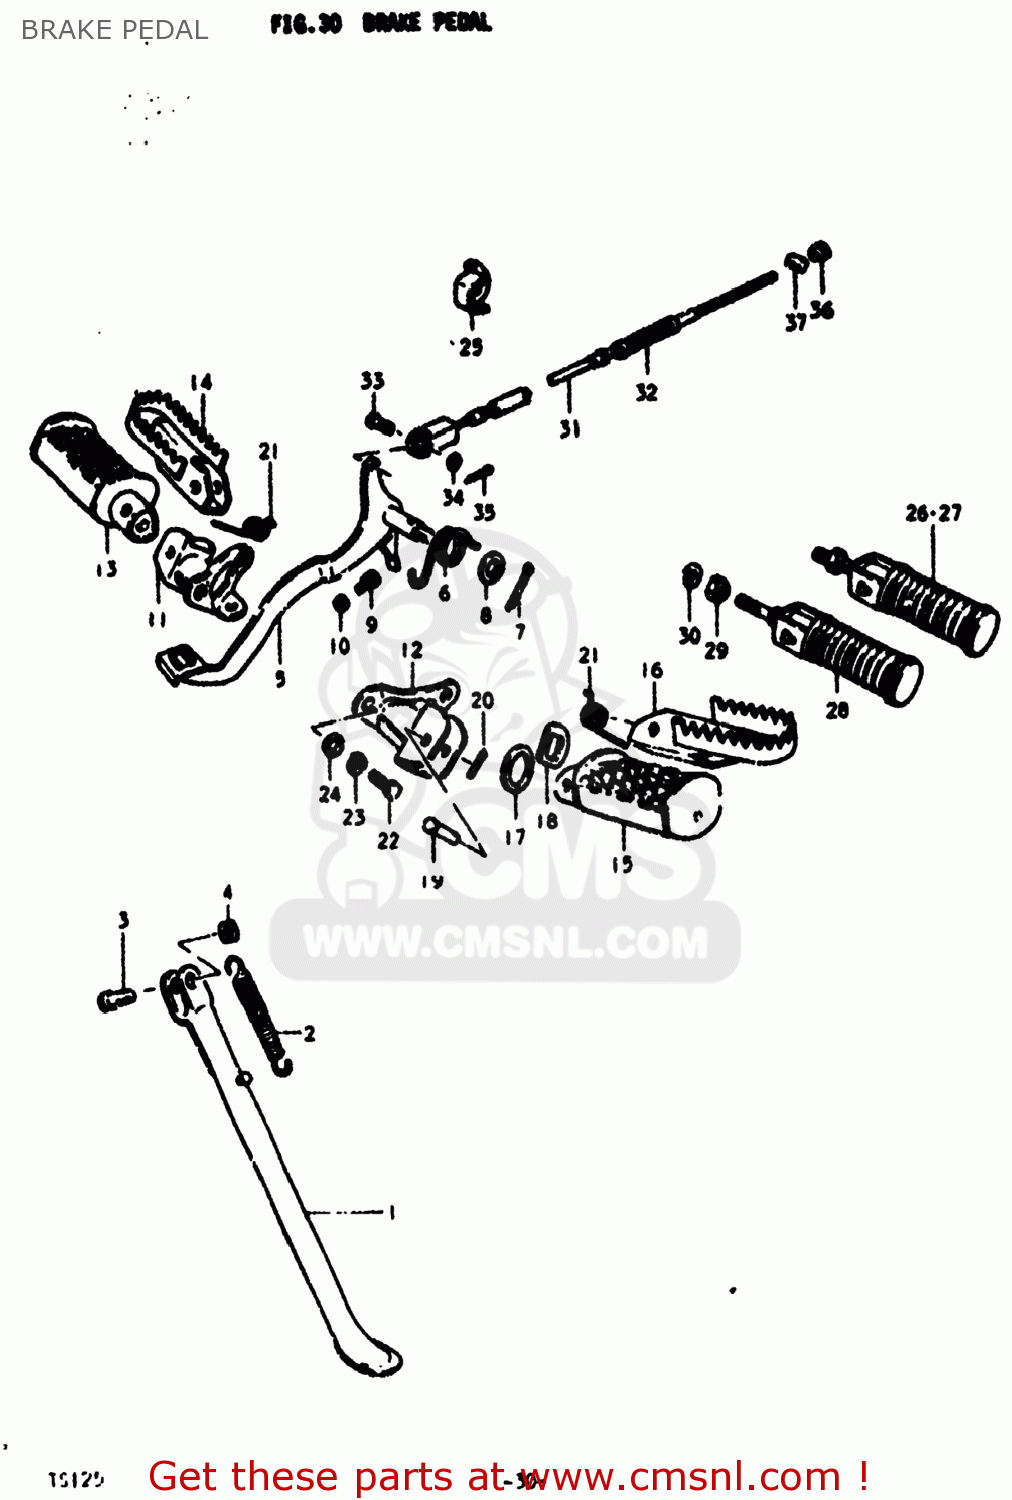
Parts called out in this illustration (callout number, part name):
1	STAND,SIDE
2	SPRING
3	BOLT(10X30)
4	NUT
5	PEDAL,BRAKE
6	SPRING
7	COTTER PIN
8	WASHER(15.5X26X2.3)
9	BOLT
10	NUT
11	BAR,FRONT FOOTREST
12	HOLDER,FRONT FOOTREST
13	RUBBER,FOOTREST,RIGHT
14	RUBBER,FOOTREST,RIGHT
15	RUBBER,FOOTREST,LEFT
16	RUBBER,FOOTREST,LEFT
17	WASHER
18	WASHER
19	PIN
20	PIN 20X20
21	SPRING
22	BOLT
23	LOCK WASHER
24	WASHER
25	HOLDER
26	FOOTREST ASSEMBLY,REAR
27	FOOTREST ASSEMBLY,REAR
28	FOOTREST ASSY,PILLION
29	NUT
30	WASHER,LOCK 12
31	CABLE,RR BRAKE
32	SEAL,DUST
33	PIN
34	WASHER
35	PIN
36	NUT
37	PIN(11X18)
